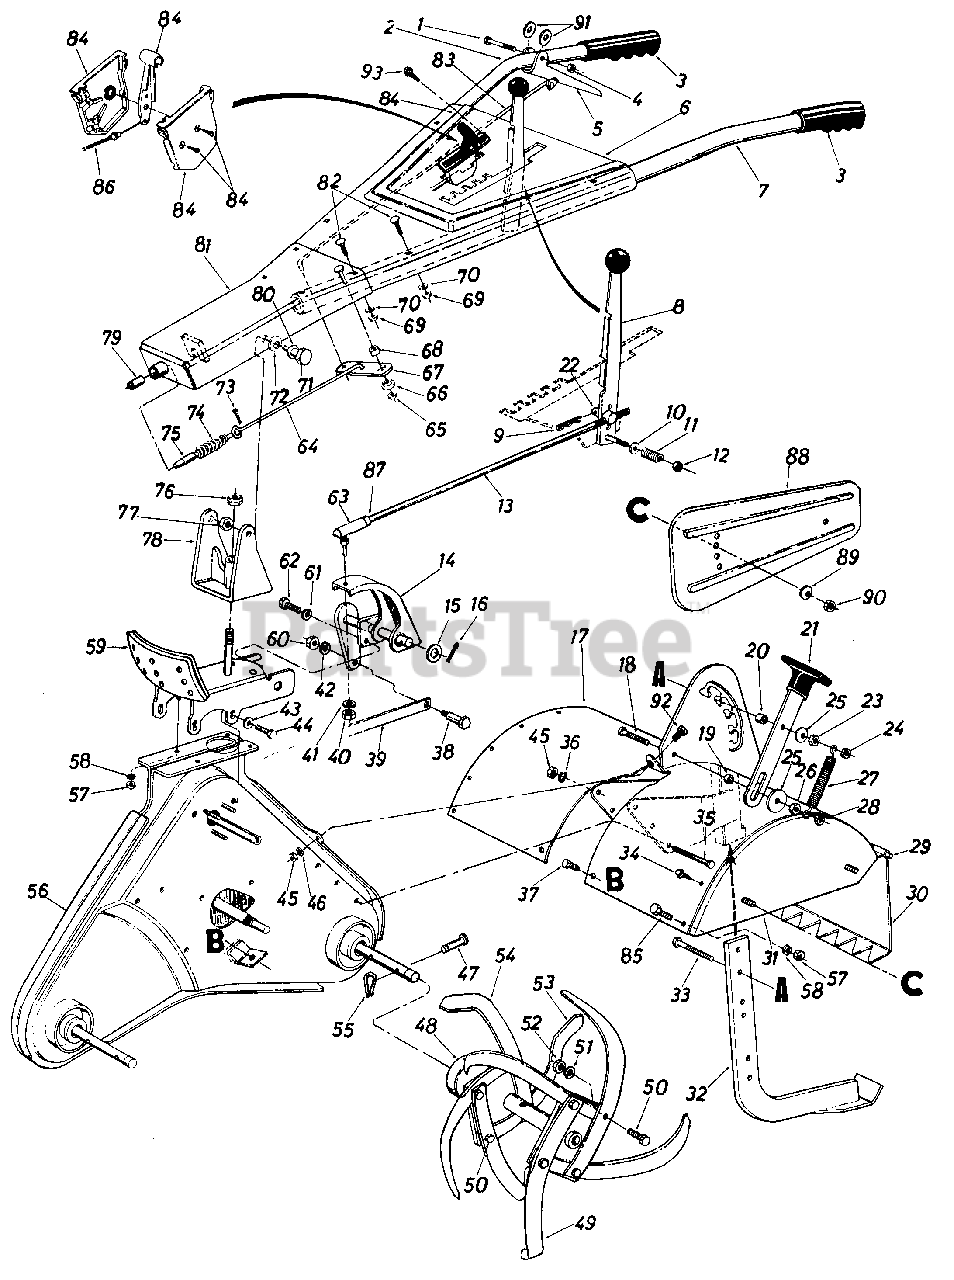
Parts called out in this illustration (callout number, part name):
1	Hex Bolt 1/4-20 x 1.75" Lg.*
2	Handle-R.H.
3	Grip
4	Hex Cent. L-Nut 1/4-20 Thd.
5	Clutch Grip
6	Handle Panel Ass'y.
7	Handle-L.H.
8	Clutch Handle Ass'y.
9	Hairpin Cotter
10	Belleville Wash. .38" I.D.
11	Compression Spring .88" O.D. x .81" Lg.
12	Hex Cent. L-Nut 3/8-24 Thd.
13	Gear Shift Rod
14	Pivot Horn Ass'y.
15	Fl-Wash. .630 I.D. x 1.0" O.D. x .063
16	Cotter Pin 1/8" Dia. x .75" Lg. *
17	Tine Shield Ass'y.
18	Hex Bolt 3/8-16 x 1.5" Lg.*
19	Spacer .38 I.D. x .50 O.D. x .18 Lg.
20	Spacer .38 I.D. x .50 O.D. x .38 Lg.
21	Depth Bar Handle Ass'y. w/Knob
22	Ferrule
23	Hex Nut 3/8-16 Thd.*
24	Hex Ins. L-Nut 3/8-16 Thd.
25	Fl-Wash. .38 I.D. x 1.50 O.D. x .13
26	Hex Nut 3/8-16 Thd.*
27	Spring-Depth Bar
28	Hex Ins. L-Nut 3/8-16 Thd.
29	Hinge Rod
30	Tine Shield Hinge Flap Ass'y.
31	Side Cover Tine Shield-L.H.
32	Depth/Drag Bar Ass'y.
33	Hex Bolt 3/8-16 x 1.75" Lg.*
34	Hex Wash. Hd. Self-Tap Scr. 5/16-18 x .62" Lg.
35	Hex Bolt 3/8-24 x 3.0" Lg.
36	L-Wash. 3/8" I.D.*
37	Hex Wash. Hd. Self-Tap Scr.
38	Shoulder Bolt .50" Dia. x .25" Lg.
39	Control Bracket
40	Hex Ins. L-Nut 3/8-24 Thd.
41	L-Wash. 3/8" I.D.*
42	L-Wash. 3/8" I.D.*
43	Belleville Wash.
44	Hex Wash. Hd. Self-Tap Scr.
45	Hex Nut 3/8-24 Thd.*
46	L-Wash. 3/8" Scr.
47	Clevis Pin
48	Tine Adapter Ass'y.
49	L.H. Tine Ass'y. Comp.
50	Hex Bolt 3/8-24 x 1.25" Lg.
51	L-Wash. 3/8" I.D.*
52	Hex Nut 3/8-24 Thd.
54	Tine-L.H.
55	Hairpin Cotter
56	Chain Case Ass'y. Comp.
57	Hex Nut 5/16-18 Thd.
58	L-Wash. 5/16" I.D.
59	Handle Positioner Ass'y.
60	Hex Ins. L-Nut 3/8-16 Thd.
61	L-Wash. 5/16" I.D.
62	Hex Wash. Hd. Self-Tap Scr.
63	Rod End 3/8-24 Thd.
64	Lower Handle Control Rod
65	Hex Nut 5/16-18 Thd.
66	Pivot Handle Brg.
67	Pivot Handle Link
68	Bushing Wash.
69	Hex Nut 5/16-18 Thd.
70	L-Wash. 5/16" I.D.
71	Shld. Bolt .500" Dia. x .660
72	Belleville Wash. .505" I.D. x 1.00" O.D.
73	Cotter Pin 118" Dia. x .75" Lg.
74	Compression Spring
75	Locking Pin
76	Hex Ins. L-Nut 5/8-16 Thd.
77	Hex Top L-Nut 3/8-16 Thd.
78	Pivot Brkt. Ass'y.
79	Sleeve Brg. .50" I.D. x .62" O.D. x 1.12" Lg.
80	Fl-Wash. .50" I.D. x 1.00" O.D. x .090
81	Handle Mtg. Brkt. Ass'y.
82	Carriage Bolt 5/16-18 x 1.75" Lg.
83	Handle Lock Rod
84	Throttle Control Box Ass'y.
85	Hex Bolt 5/16-18 x .75" Lg.
86	Throttle Control Wire
87	Hex Jam Nut 3/8-24 Thd.
90	Hex Nut 5/16-18 Thd.
91	Fl-Wash. 1/4" I.D.
92	Hex Bolt 3/8-24 x .75" Lg.
93	Self-Tap Scr. #10 x 1/2" Lg.
